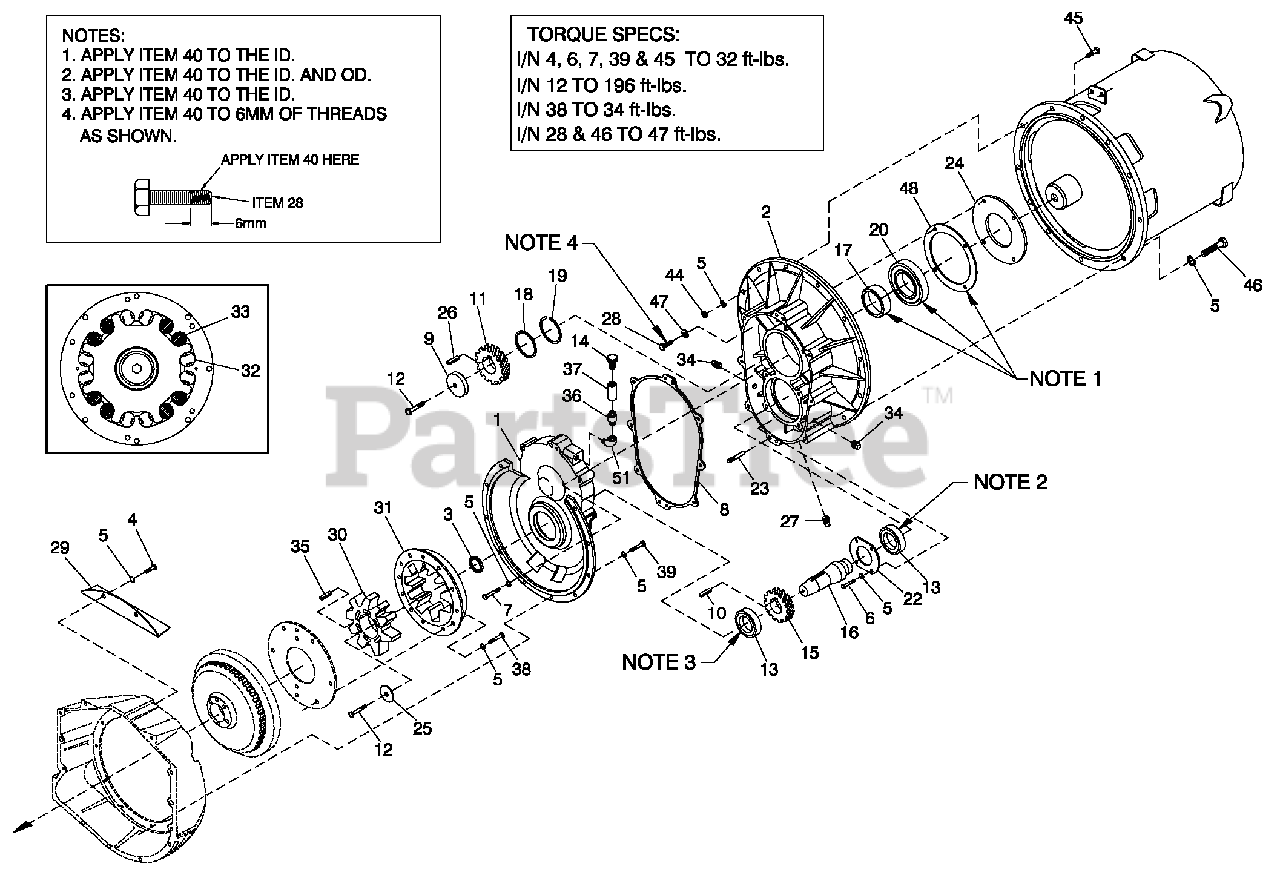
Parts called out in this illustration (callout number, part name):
1	GEAR CASE ENG. MACHINED
2	GEAR CASE ALT. MACHINED
3	SEALOIL
4	SCREW HHC M10-1.5X 20 G8.8
5	WASHER LOCK M10
6	SCREW HHC M10-1.5X 25 G8.8
7	SCREW HHC M10-1.5X 70 G8.8
8	GASKET 390 GEAR BOX
9	SPACER .69 X 2.75 X .37 ST/ZNC
10	KEY 10 X 16 X 4
11	GEAR OUTPUT 1.65:1
12	SCREW HHC M16-2.0 X 35 G10.9
13	BALLBRG 65 X 120 X 23
14	BREATHER
15	GEAR INPUT 1.65:1
16	SHAFT 390 INPUT GEAR
17	COLLAR HARDENED
18	SEALOIL
19	SNAP RING INT 120MM
20	BEARING #6213 SEALED
22	PLATE INTRNLBRG RET
23	PIN DOWEL M8 X 24
24	PLATE BEARING THRST
25	SPACER STRESSPROOF
26	KEY 10 X 16 X 40
27	PLUG PIPE 3/8"MAGNETIC
28	SCREW HHFC M10-1.5X 25 G10.9
29	COVER GEARBOX GUARD
30	COUPLING INNER DRAWN
31	COUPLING OUTER MACHN
32	DAMPER GB CPLRVIBRA
33	DAMPER GB CPLRVIBRA
34	PLUG STD PIPE 3/8 STEEL SQ HD
35	KEY 10 X 16 X 50
36	NIPPLE PIPE3/8NPTX 3-1/2
37	COUPLING FULL 3/8-18
38	SCREW HHC 3/8-16 X1-1/2G8
39	SCREW HHC M10-1.5X 25 G8.8
40	RETAINING COMPOUND
44	NUT HEX M10-1.5 G8 YEL CHR
45	SCREW HHC M10-1.5X 60 G8.8
46	SCREW HHC M10-1.5X 40 G10.9
47	WASHER FLAT M10 SEALING COPPER
48	GASKET SEAL PLATE 390 GB
50	THREADLOCK AND SEALANT
51	ELBOW 90D STREET 3/8
